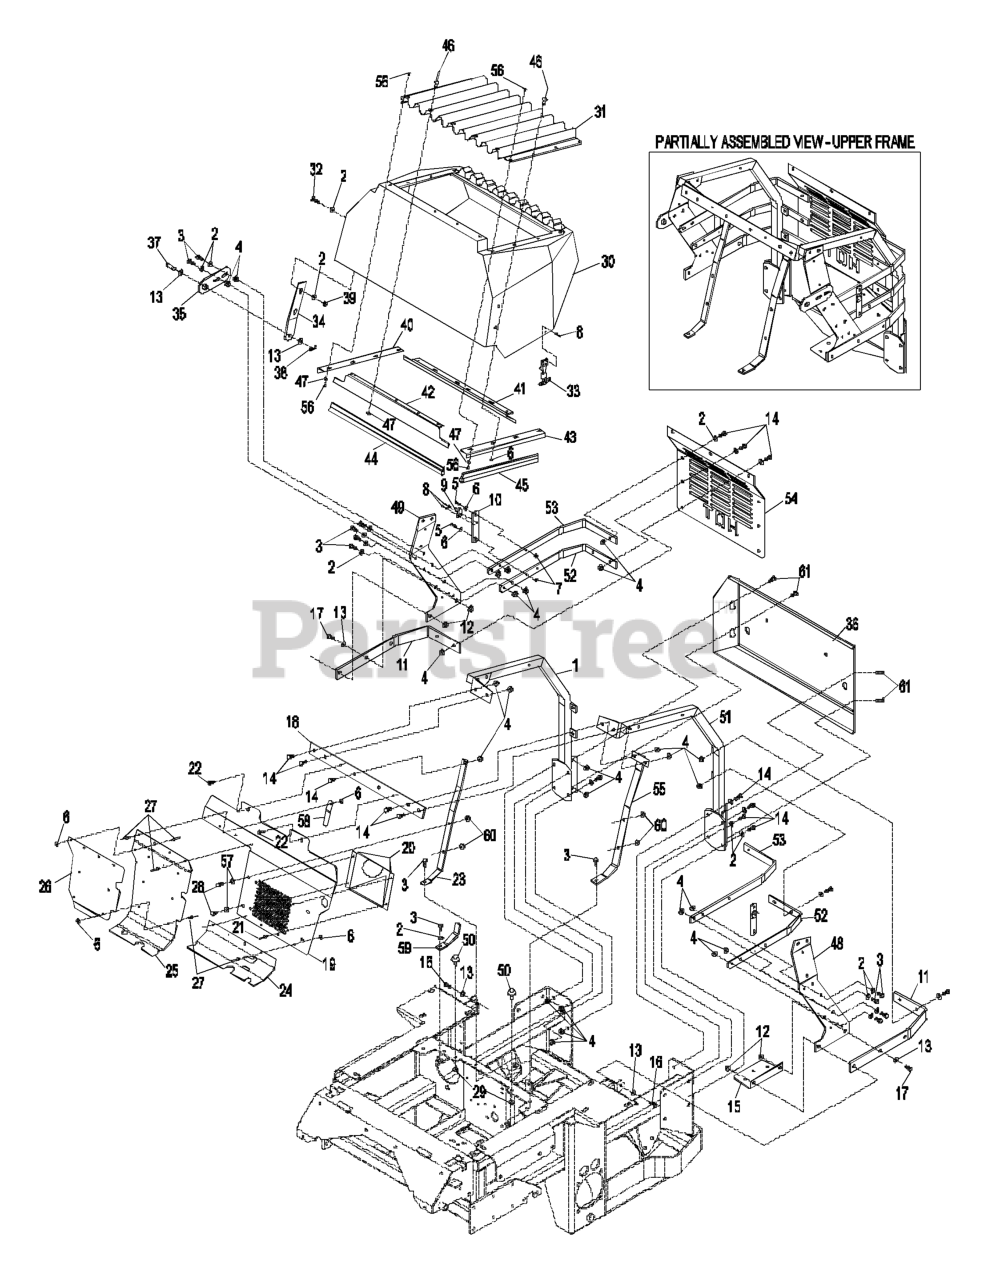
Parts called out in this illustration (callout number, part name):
1	WLD,RH REAR UPPER FRAME
2	WASHER-PLAIN
3	SCREW-HH
6	WASHER-FLAT
7	NUT-LOCK, NI
10	BAR-HOOK, LATCH
12	NUT-HHF, WHIZ
13	WASHER-FLAT
14	SCREW-HH
15	BRACKET,BOTTLE
16	SCREW-HH
17	SCREW-HH
20	PLENUM,AIR INTAKE
21	RIVET-POP
22	SCREW-HWHTF
23	BRACE,RADIATOR RH
27	RIVET-POP
28	SCREW-HH
29	NUT-LOCK, NI
31	SCREEN-RADIATOR
32	SCREW-HH
33	LATCH-RUBBER
34	PLATE-HINGE, HOOD
35	SHACKLE-HINGE
36	WLD,REAR BUMPER
37	PIN-CLEVIS
38	PIN-COTTER
39	NUT-LOCK, NI
40	ANGLE-RADIATOR, RH
41	ANGLE-RADIATOR, BOTTOM
42	ANGLE-RADIATOR, TOP
43	ANGLE-RADIATOR, LH
44	SEAL-TRIM
45	SEAL-TRIM
47	WASHER-SPRING
52	RIB,BOTTOM
55	WLD,RAD BRACE&MTG BAR
57	WASHER-FLAT
58	CLIP-BAFFLE, REAR
61	SCREW-HHF
